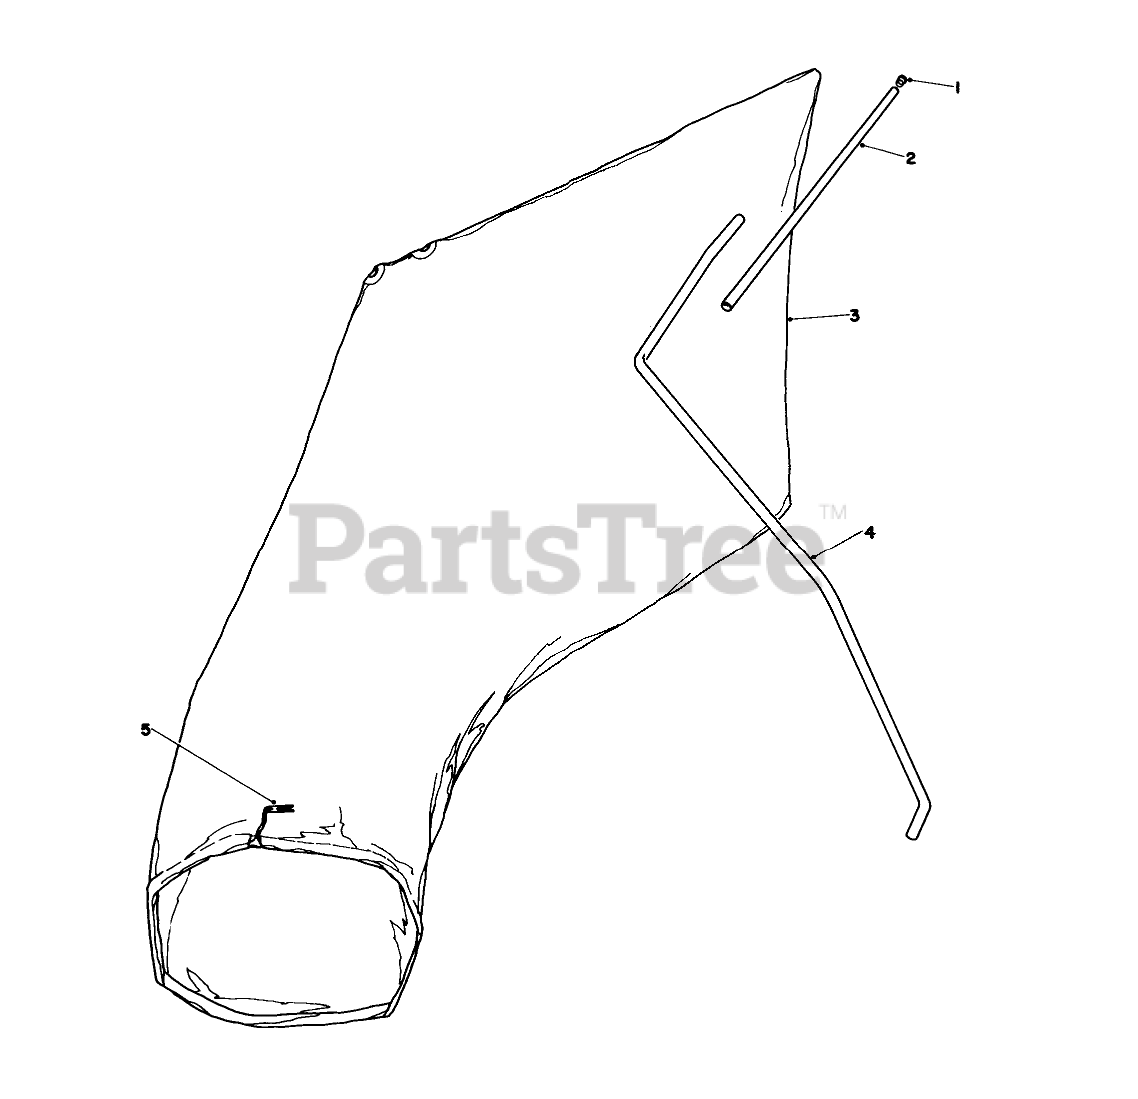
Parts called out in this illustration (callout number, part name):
2	BAG HANGER TUBE
3	Bag (Incl. Ref. #5)
4	HANGER ROD
5	BAG CORD FASTENER
